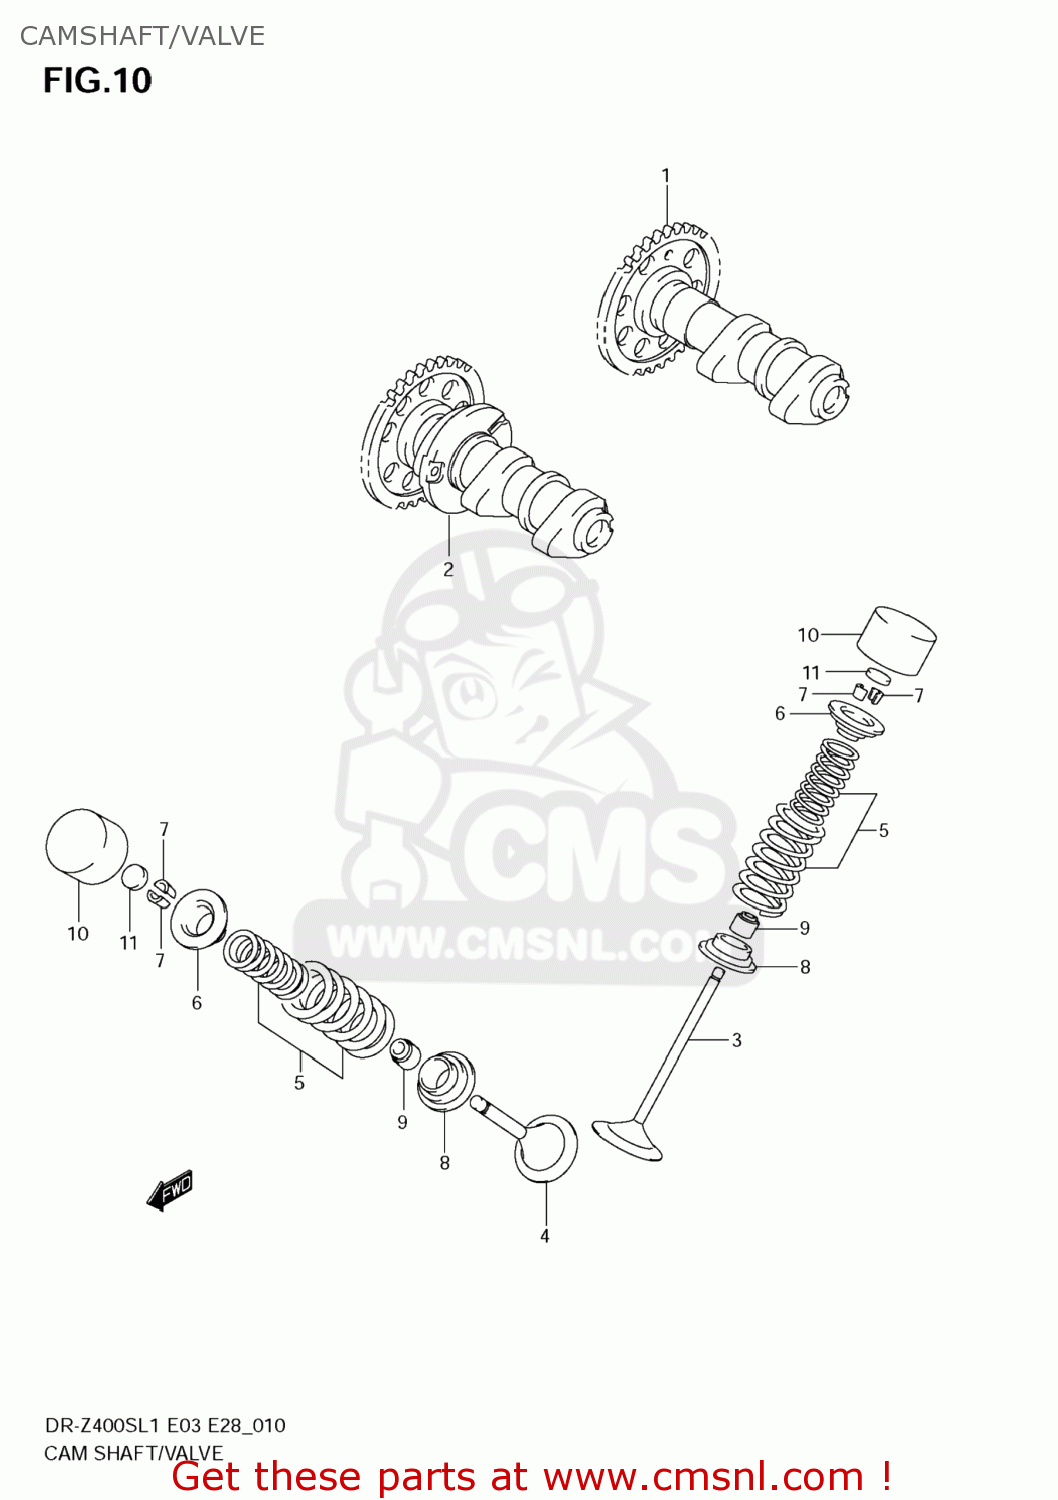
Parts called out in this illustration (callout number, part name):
1	CAMSHAFT,INTAKE
2	CAMSHAFT,EXHAUST
3	VALVE,INTAKE
4	VALVE,EXHAUST
5	SPRING SET,VALVE
6	RETAINER,VALVE SPRING
7	COTTER VALVE
8	SEAT,VALVE SPRING
9	SEAL,OIL(5X10X9.7)
10	TAPPET
11	SHIM,TAPPET(T:2.3)
12	SHIM SET,TAPPET
13	CASE,TAPPET SHIM
